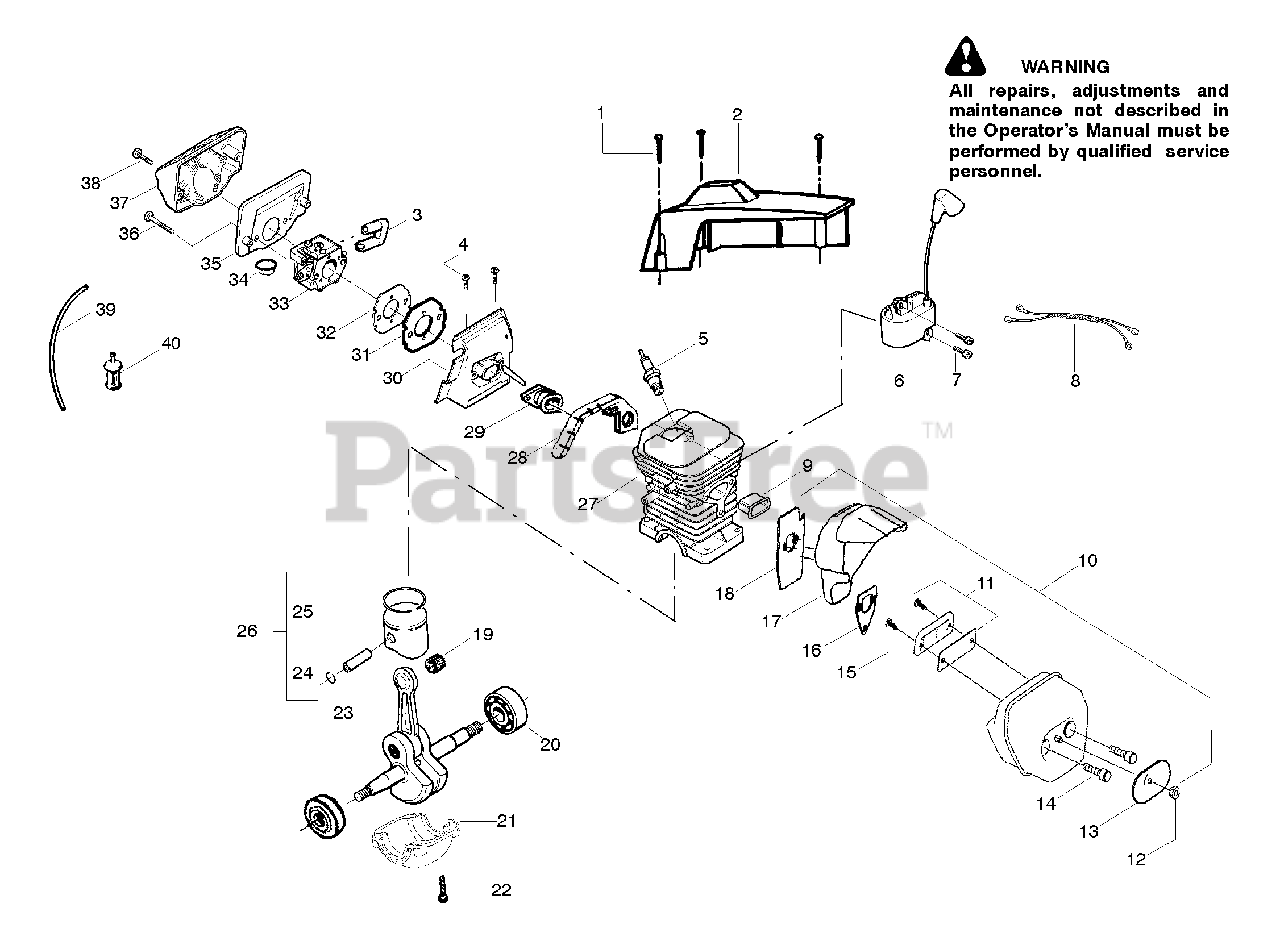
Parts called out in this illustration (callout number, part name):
2	Kit-Cylinder Shield
3	Grommet -Carb.
5	Spark Plug
6	Module-Ignition
8	Assy-Switch Wire
9	Insulator-Heat
10	Kit-Muffler
11	Kit-Spark Arrestor
12	Nut-Brass
13	Cover-Bolt
14	Bolt-Muffler
15	Screw-Spark Screen
16	Gasket-Muffler
17	Assy-Muffler Backplate
18	Backplate - Alum.
19	Bearing-Piston Pin
20	Assy-Bearing & Seal
21	Cap-Crankcase
23	Assy-C'shaft & Rod
24	Retainer-Piston Pin
25	Ring-Piston
26	Kit-Piston
27	Assy-Cyl/Crankcase
28	Seal-Super Clean
29	Intake Boot
30	Adapter-Carb.
31	Intake Plate-Carb
32	Gasket-Carb.
33	Kit-Carburetor
34	Isolator
35	Filter-Air
37	Filter-Air
39	Kit-Fuel Line
40	Assy-Fuel Pick-up
